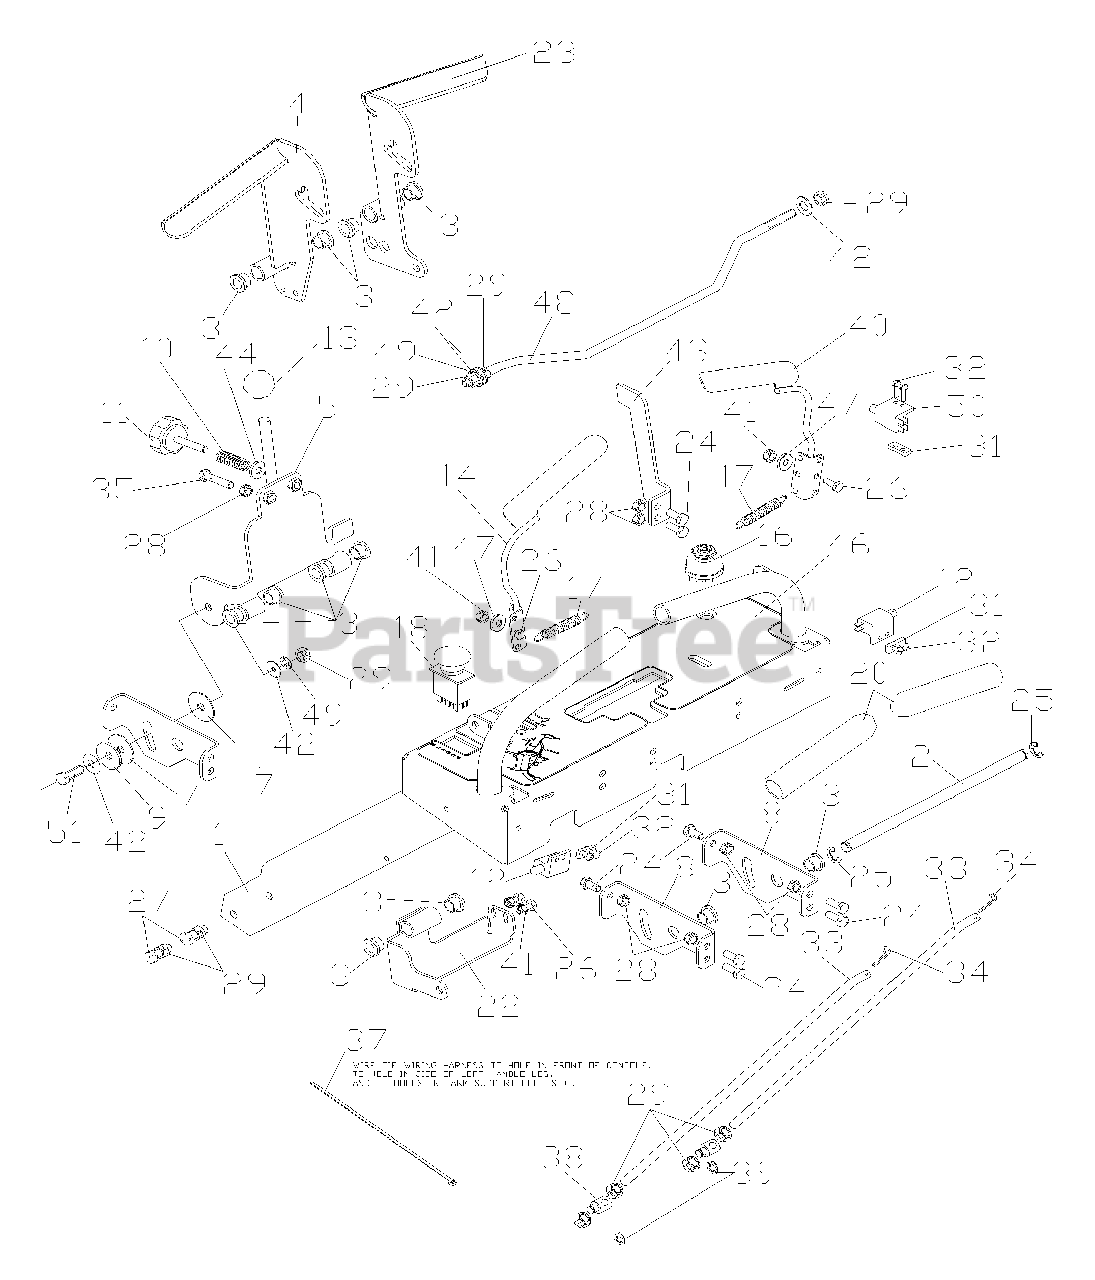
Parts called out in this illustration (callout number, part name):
3	FLANGE BUSHING
4	PADDLE LH.
5	NEUTRAL BAR
7	FRICTION WASHER
8	CROSSBRACE
9	WASHER 1/2 FLAT
12	SWITCH N.C.
14	OP LEVER LH.
16	IGNITION SWITCH W/KEY
18	CLUTCH SWITCH
22	TAB WLDMT. LH.
23	PADDLE RH.
24	HCS 5/16 X .750
25	E-RING 1/2
26	HCS 1/4 X .625
27	HCS 3/8 X 1.000
28	NUT 5/16 CTR. LOCK
29	NUT 3/8 CTR. LOCK
31	TAPPED PLATE
32	SCREW #10-24
34	COTTER PIN
35	HCS 5/16 X 1.250
40	OP LEVER RH.
41	NUT 1/4 CTR. LOCK
42	WASHER 3/8 FLAT
43	STOP PLATE
44	WASHER 5/16 FLAT
46	CONSOLE DECAL
47	WASHER 1/4 FLAT
48	NUETRAL BAIL
49	WASHER 3/8 LOCK
50	SAFETY SWITCH
51	HCS 3/8 X 1.250
